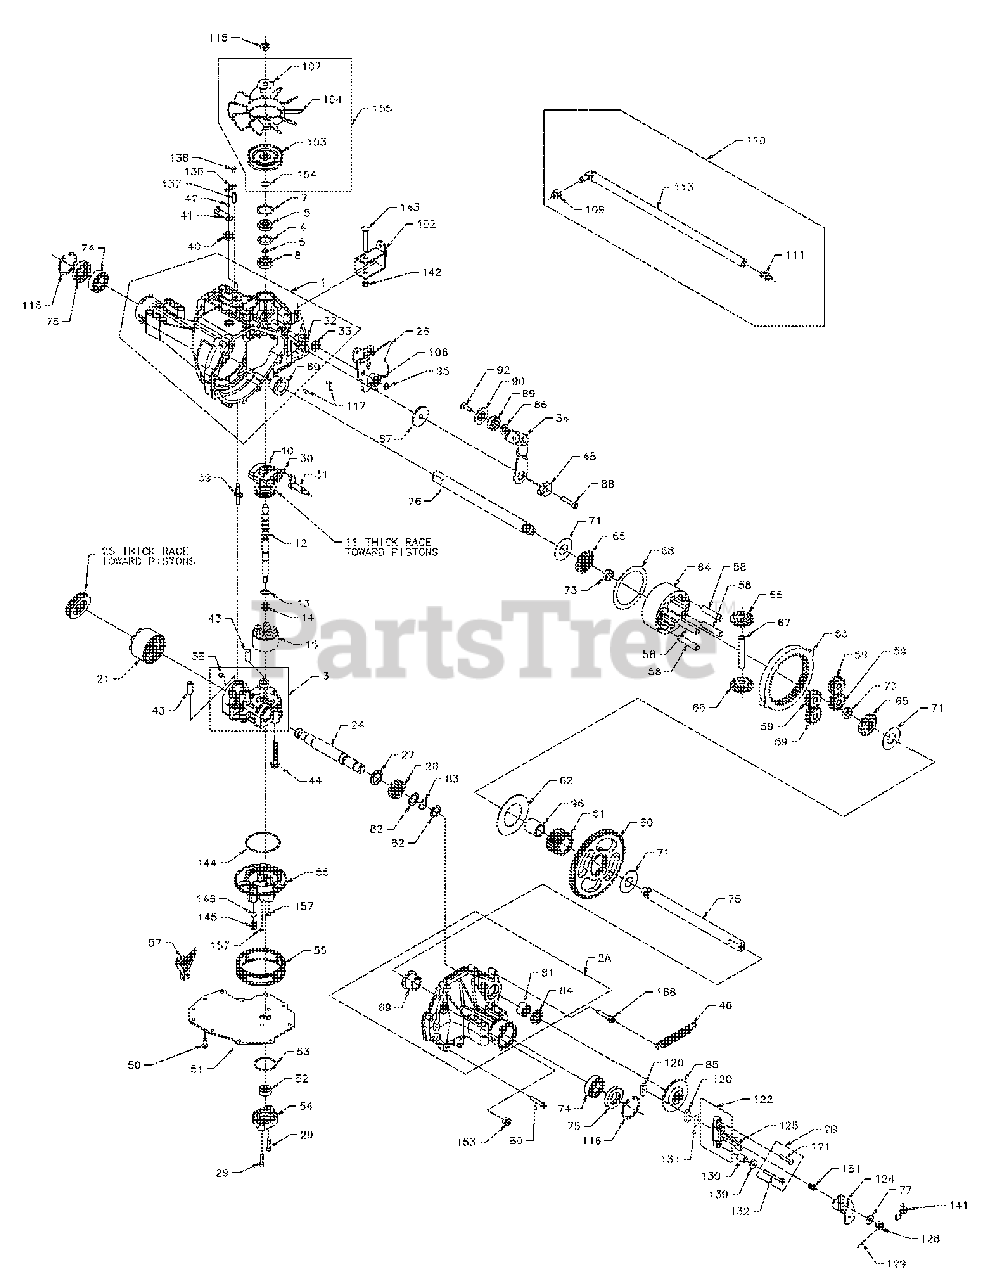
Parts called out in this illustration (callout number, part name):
1	Assembly, Main Housing
2A	Assembly, Right Hand Housing
2B	Kit, Brake Bolt
3	Assembly, Center Section
4	Spacer, .98 x 1.37 x .04
5	Seal, Lip 15 x 35 x 7
6	Ring, Retaining
7	Ring, Retaining
8	Bearing, Ball .59 x 1.38 x .43
10	Swashplate, Variable
11	Bearing, Thrust 30 x 52 x 13
12	Shaft, Input (STD Charge)
13	Washer, Thrust .59 x .79 x .04
14	Spring, Block
15	Assembly Block
21	Assembly Block
24	Shaft, Motor
25	Bearing, Thrust 42 x 68 x 16
26	Arm Control
27	Spacer, 1.03 x 1.38 x .184
28	Gear, 16T Piston
29	Screw, Cap M6 x 1 x 25
30	Guide, Slot
31	Arm, /Trunnion Tapered Square
32	Bearing, Trunnion
33	Seal, Lip 12 x 25 x 7
34	Arm, Return
38	Kit, Bypass Plate
39	Actuator, Bypass
40	Seal, Lip 10 x 25 x 7
41	Arm, Bypass
42	Ring Retaining
43	Pin, Hollow .39 x .50 x 1.12
44	Screw, Hex Flange 3/8-24 x 2.5
46	Spring, 5 inch Return (medium)
48	Puck , Adjusting
50	Screw, Hex Flange 1/4-20 x .75
51	Cover, Lower w/2 Kidneys
53	O-Ring, 1.862 x 2.068
54	Housing, Charge Pump
55	Kit, Filter
56	Manifold, Charge
57	Retainer, Motor Bearing
58	Pin, Carrier
59	Gear 15T Planet
60	Gear, 67T Spur
61	Gear, 21T Sun
62	Washer, Thrust 2.32 x 4.10 x .05
63	Gear, 51T Ring
64	Carrier Planetary
65	Gear 14T Miter (Splined)
66	Gear 14T Miter (Unsplined)
67	Shaft, Differential
68	Washer, Thrust 3.46 x 4.39 x .05
69	Bearing, Flange 1.0 x 1.376 x .99
71	Washer, 1.0 x 2.25 x .04
73	Nut, Hex 5/8-18 w/Patch
74	Bearing, Ball 25.4 x 52 x 15
75	Seal, lip 1.0 x 2.049 x .375
76	Shaft, Axle 1 x 12.69 (DD)
77	Washer, .34 x .88 x .06
79	Sealant (10.1 oz)
80	Screw, Torx, HD 5/16-18 x 1.5
81	Bearing, Needle .875 x 1.125 x 1.5
82	Washer, Flat .88 x 1.25 x .04
83	Ring, Retaining
84	Seal, Lip .875 x 1.375 x .250
85	Disk, Brake
86	Washer, .51 x 1.0 x.03
87	Spacer, .32 x 1.96 x .15
88	Screw, Socket HD Cap 5/16 x 1.5
89	Bearing, Ball .62 x 1.38 x .44
90	Spacer, Locating
92	Screw, Countersunk 5/16 - 18 x 1.0
95	Nut, Hex Lock 5/16-24
96	Brushing, Sleeve 1.0 x 1.3 x 1.34
102	Bracket, Torque
103	Pulley, 3.6 inch
104	Fan, 7.0 In (10 blade)
106	Spacer, Trunnion
107	Washer, OD Slotted 53 x 1.363 x .06
109	Bushing Vent (Rubber)
110	Kit Fitting
111	Assembly, Cap-vent
113	Kit, 90 Degree Fitting and Hose Assembly
115	Nut, Hex 1/2 -20 W/Patch
116	Ring, Retaining
117	Pin, Standard Headless
120	Puck, Brake
121	Bolt, Hex HD 1/4-20 x 1.25 w/Patch (order kit)
122	Assembly, Brake w/Yoke
124	Arm, Brake
125	Pin, Brake Actuating
128	Nut, Castle 5/16-24
129	Pin, Cotter 3/32 x 3/4
130	Spacer, .326 x .57 x.87
131	Plate, Puck
132	Bolt, Hex HD 1/4-20 x 1.25 w/Patch (order kit)
136	Spring, Bypass 1.33 inch extension
137	Pin, spring .26 x 1
138	Bolt, Self tapping 10-32 x .5
139	Washer, .27 x .88 x .2
141	Spring, Brake Arm Bias
142	Nut, Hex Lock 5/16-18
143	Bolt, 5/16-18 x 2.5
144	O-Ring, 2.987 x 3.09
145	Spring, Relief
151	Spring, Comp. Brake Anti-Drag
153	Plug 9/16-18 (metal)
154	Ring, Retaining
155	Kit, Fan/Pulley Components
157	O-Ring .239 x .379
168	Screw, Torx HD Shouldered 5/16-18 x 1.81
203	Kit, Seal & O-Ring
